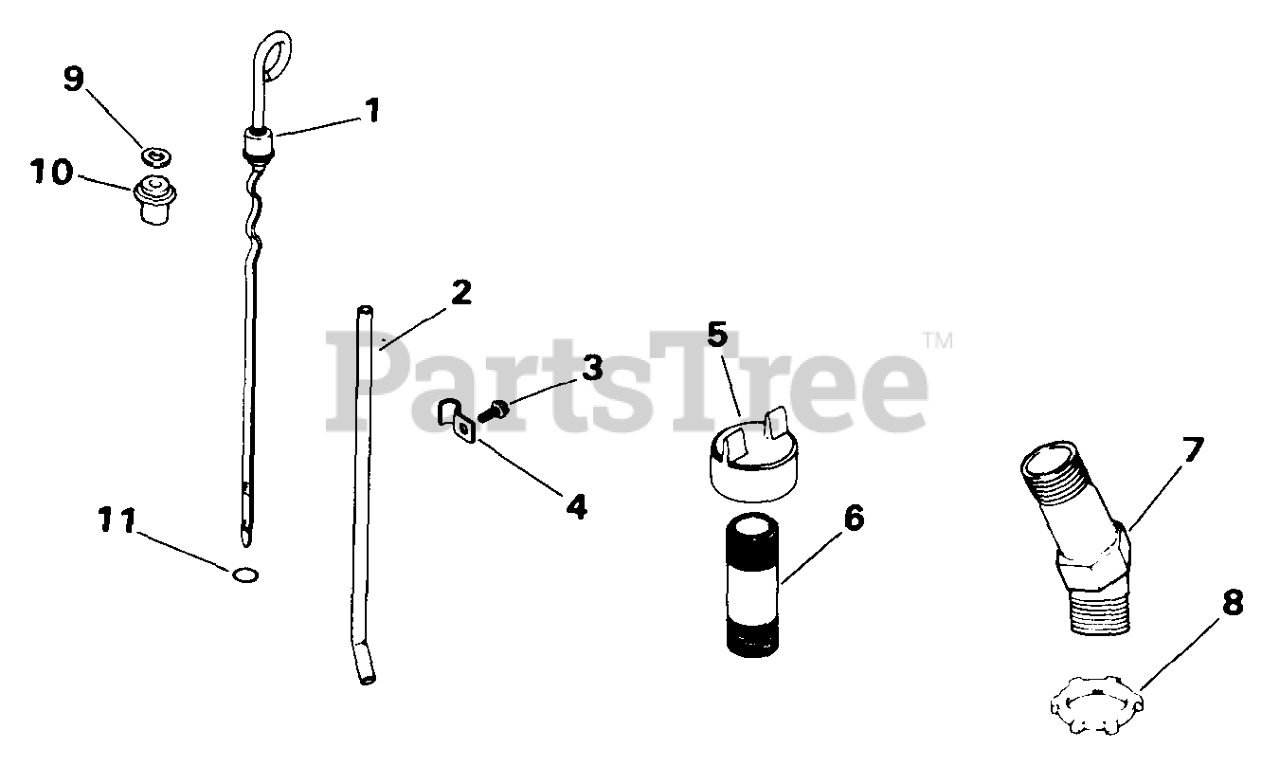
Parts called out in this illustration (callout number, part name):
1	Dipstick 11-5/16" Blade
2	Tube, Oil Level
3	Screw, Hex. Wash. Hd. 10-32x7/16"
4	Clip, Tube
5	Cap, Pipe
6	Pipe, 1" N.P.T.F. X 3"
